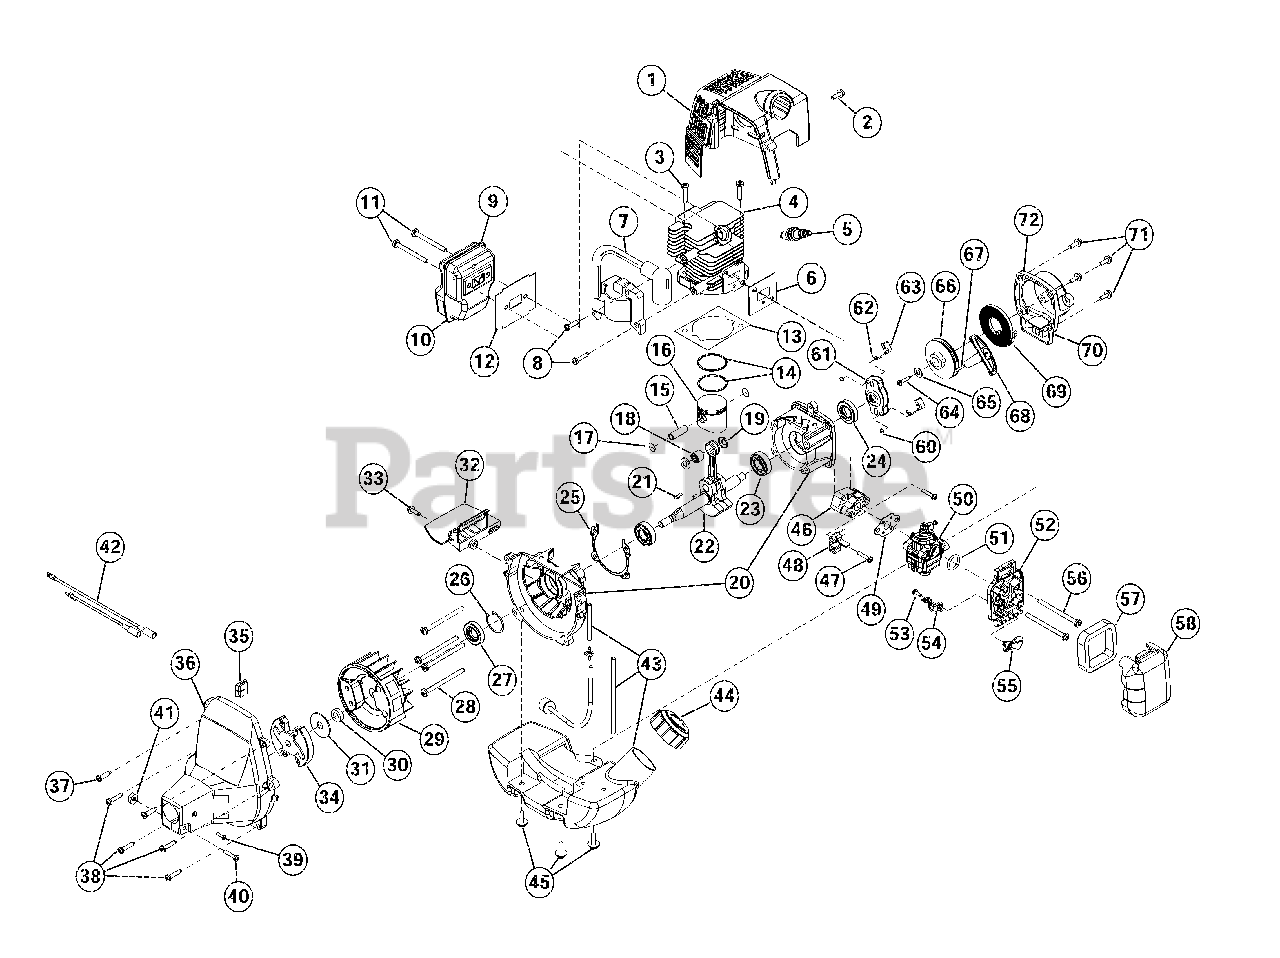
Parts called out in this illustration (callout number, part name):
1	Engine Cover
2	Cover Screw
3	Cylinder Bolt
6	Insulator Gasket
7	Module Assembly
8	Module Screw
9	Muffler Assembly
11	Muffler Mounting Bolt
12	Muffler Gasket
13	Cylinder Gasket
18	Needle Baring
19	Piston Spacer
20	Crankcase Assembly
22	Crankshaft Assembly
24	Rear Oil Seal
25	Crankcase Gasket
27	Front Oil Seal
28	Crankcase Screw
31	Clutch Washer
32	Muffler Plate
33	Muffler Plate Screw
35	Wire Grommet
36	Clutch Housing
37	Upper Housing Screw
38	Lower Housing Screw
39	Anti-Rotation Screw
40	Clamp Screw
42	Lead Wire Assembly
43	Fuel Tank Assembly
45	Fuel Tank Screw
47	Insulator Screw
48	Throttle Bracket
49	Carburetor Gasket
50	Carburetor
52	Air Cleaner Assembly
53	Choke Screw
54	Choke Lever
55	Choke Plate
56	Air Cleaner Screw
58	Air Cleaner Cover
59	Pawls Assembly
64	Recoil Pulley Retaining Screw
65	Recoil Pulley Retaining Washer
66	Recoil Pulley
68	Starter Handle
69	Recoil Spring
70	Recoil Pulley Cover
71	Recoil Pulley Screw
72	Recoil Assembly
